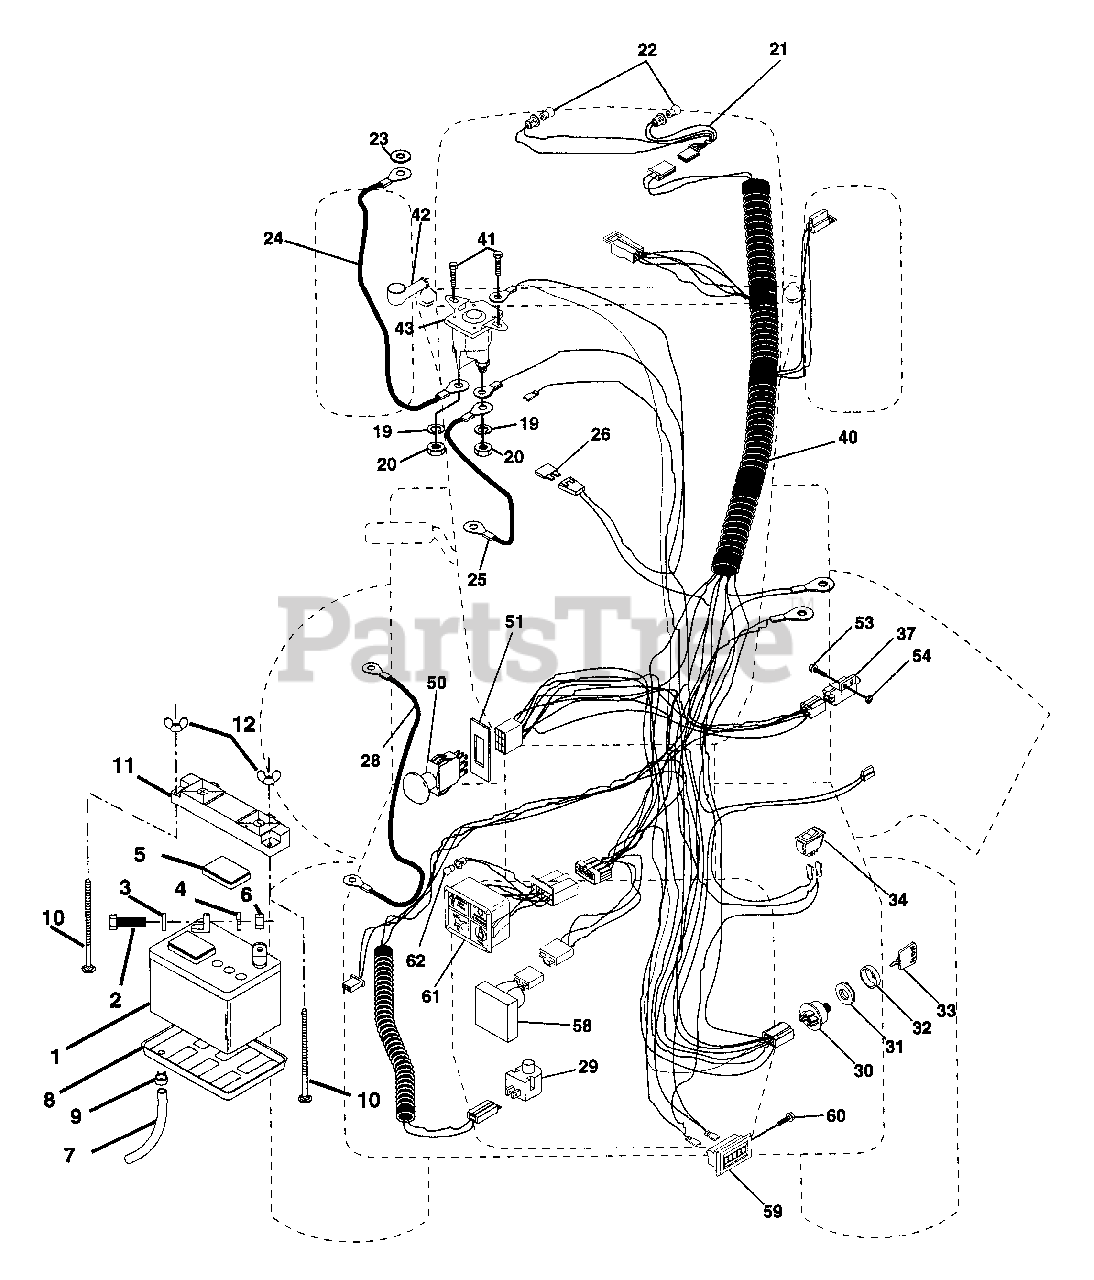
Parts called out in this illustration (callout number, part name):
1	Battery
2	Bolt Hex Head 1/4-20 x 3/4
3	Washer, Lock 1/4
4	Washer 9/32 x 5/8 x 16 Ga
5	Caps, Battery
6	Nut Fin Hex 1/4-20
7	Tube Plastic
8	Tray, Battery
9	Clamp, Hose
10	Bolt, Carriage 1/4-20 x 7-1/2
11	Guard Terminal
12	Nut, Wing 1/4-20
19	Washer, Lock 1/4
20	Nut, Jam Hex 1/4-20
21	Harness Socket Light
22	Bulb Light
23	Washer, Lock Int. Tooth 1/4
24	Cable, Starter
25	Cable, Battery
28	Cable, Ground
29	Switch, Plunger
30	Switch, Ign
31	Nut, Ignition Switch
32	Cover Switch Key
34	Switch, Light
37	Intlk Switch
40	Harness Ign.
41	Screw 1/4-20 x 1/2
42	Cover, Terminal Red
43	Solenoid
50	Switch, PTO
51	Ring Retainer PTO
53	Screw Hex Washer Hd #10-32 x 1
54	Nut Keps #10-32
58	Sensor Lo-Volt
59	Meter Hour
60	Screw #10-24 x 1/2
61	Light Pkg Asm
62	Bulb, Light Pkg.
